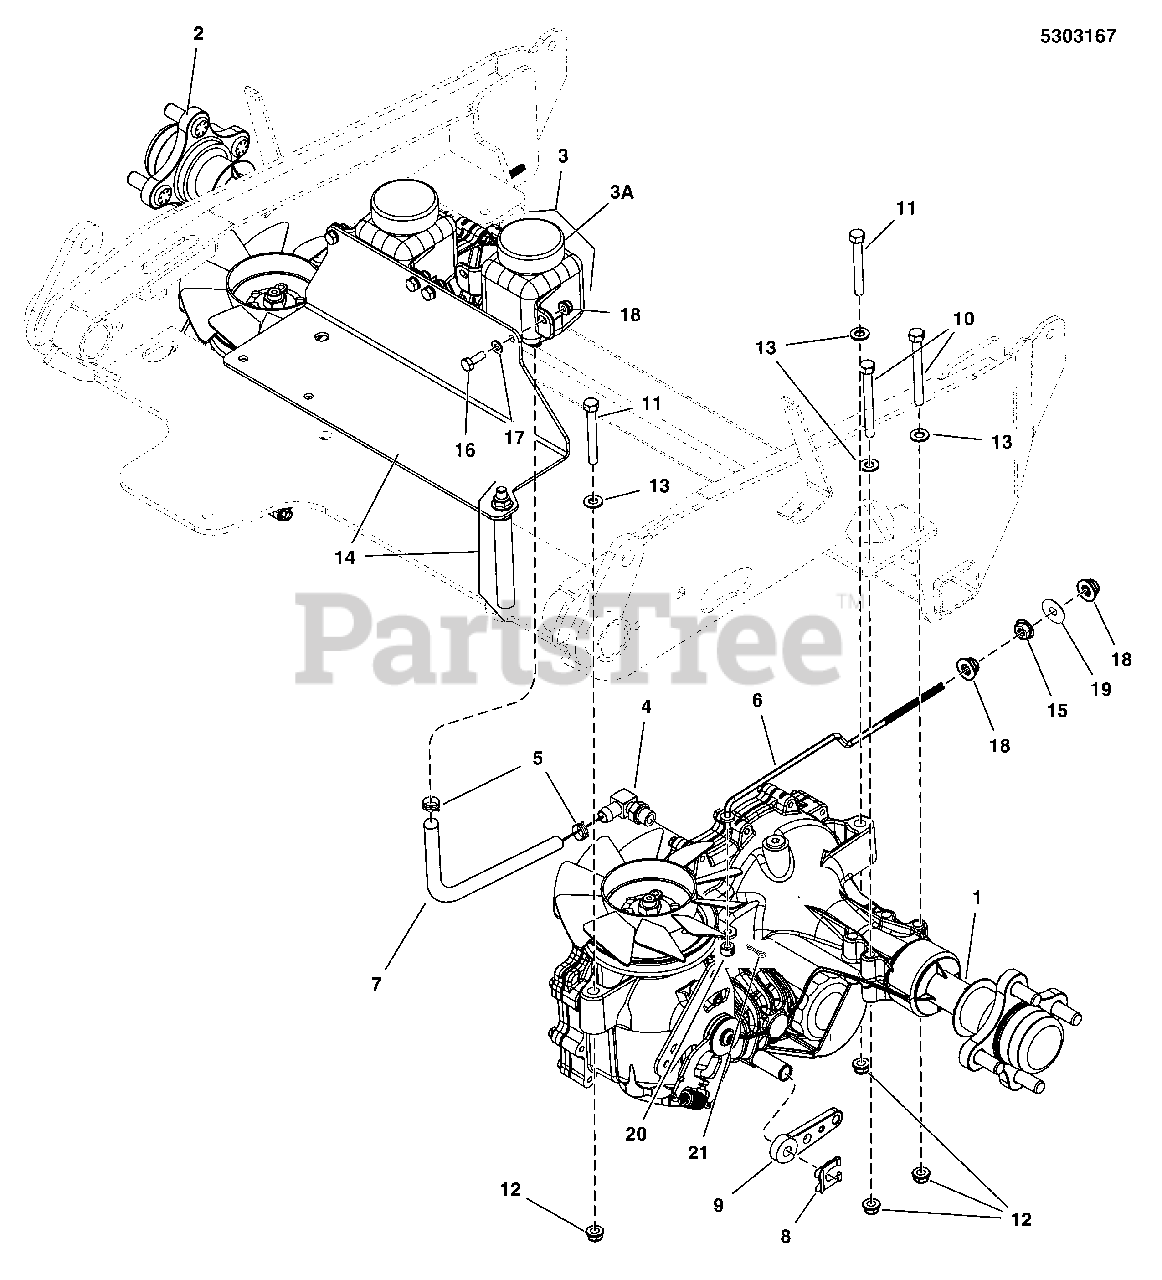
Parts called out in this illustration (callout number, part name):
1	TRANS, 3400, LH, ZS-KHEF-8T7C-11RX
2	TRANS, 3400, RH, ZS-KHEF-8T7C-11RX
3	HYDRO RES. #71328, 350 ml
3A	RESERVOIR CAP
4	FITTING, 9/16 O-RING-1/2" HOSE, 90 DEG
5	CLAMP, HOSE
6	ROD, DUMP VALVE, IS600
7	TUBING, TYGON, .50 ID X 9.50
8	E-CLIP, BRAKE ARM, ZT3100 & ZT3400
9	BRAKE ARM, ZT-3400
10	BOLT, 5/16-18 X 3 GD5 YZ
11	BOLT, 5/16-18 X 2-1/2 GD5 YZ
11	BOLT, 3/8-16 X 2-1/2 GD5
12	NUT, 5/16-18 HEX NYLOCK FLANGE
12	WASHER, 3/8 SAE
13	WASHER, 5/16 F436 FLAT
13	NUT, 3/8-16 HEX NYLOCK FLANGE
14	See Pump Drive Group
15	NUT, 1/4-20 HEX SERR. FLANGE
16	BOLT, 1/4-20 X 3/4 GD5 YZ
17	WASHER, 1/4 SAE (5025154)
18	NUT, 1/4-20 HEX NYLOCK FLANGE (5025391)
19	WASHER, 1/4 FENDER
20	COLLAR, 1/4 SET
21	PIN, HAIR, .0585 X 1-1/8, 1/4 EYE, YZ
